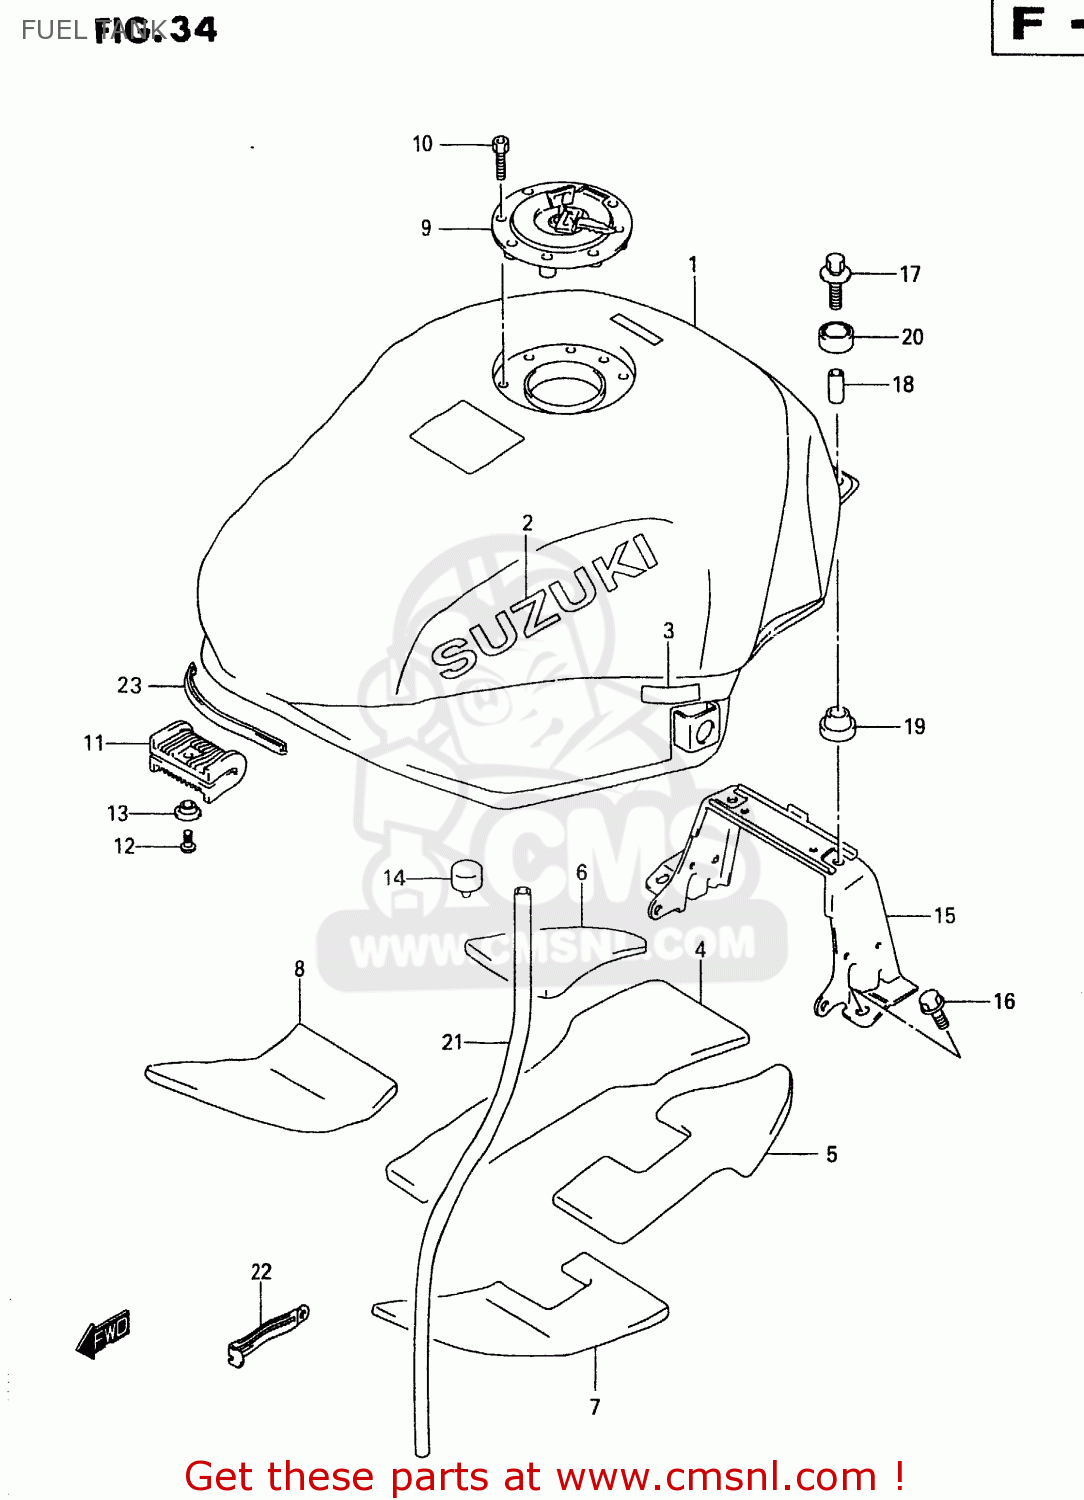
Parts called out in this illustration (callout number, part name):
1	TANK ASSEMBLY,FUEL
2	EMBLEM,FUEL TANK
3	PROTECTOR(12X40)
4	SHIELD,FUEL TANK HEAT NO.1
5	SHIELD,FUEL TANK HEAT NO.2
6	SHIELD,FUEL TANK HEAT NO.3
7	SHIELD,FUEL TANK HEAT NO.4
8	SHIELD,FUEL TANK HEAT NO.5
9	CAP SET,FUEL TANK
10	BOLT(5X20)
11	CUSHION,FUEL TANK FR
12	SCREW 5X12
13	WASHER
14	CUSHION
15	BRACKET,FUEL TANK RR
16	BOLT
17	BOLT(6X30)
18	SPACER(6.5X9X18)
19	CUSHION
20	CUSHION
21	HOSE,FUEL TANK WATER DRAIN
22	CLAMP(L:120 T:1.0)
23	MOLDING,FUEL TANK
